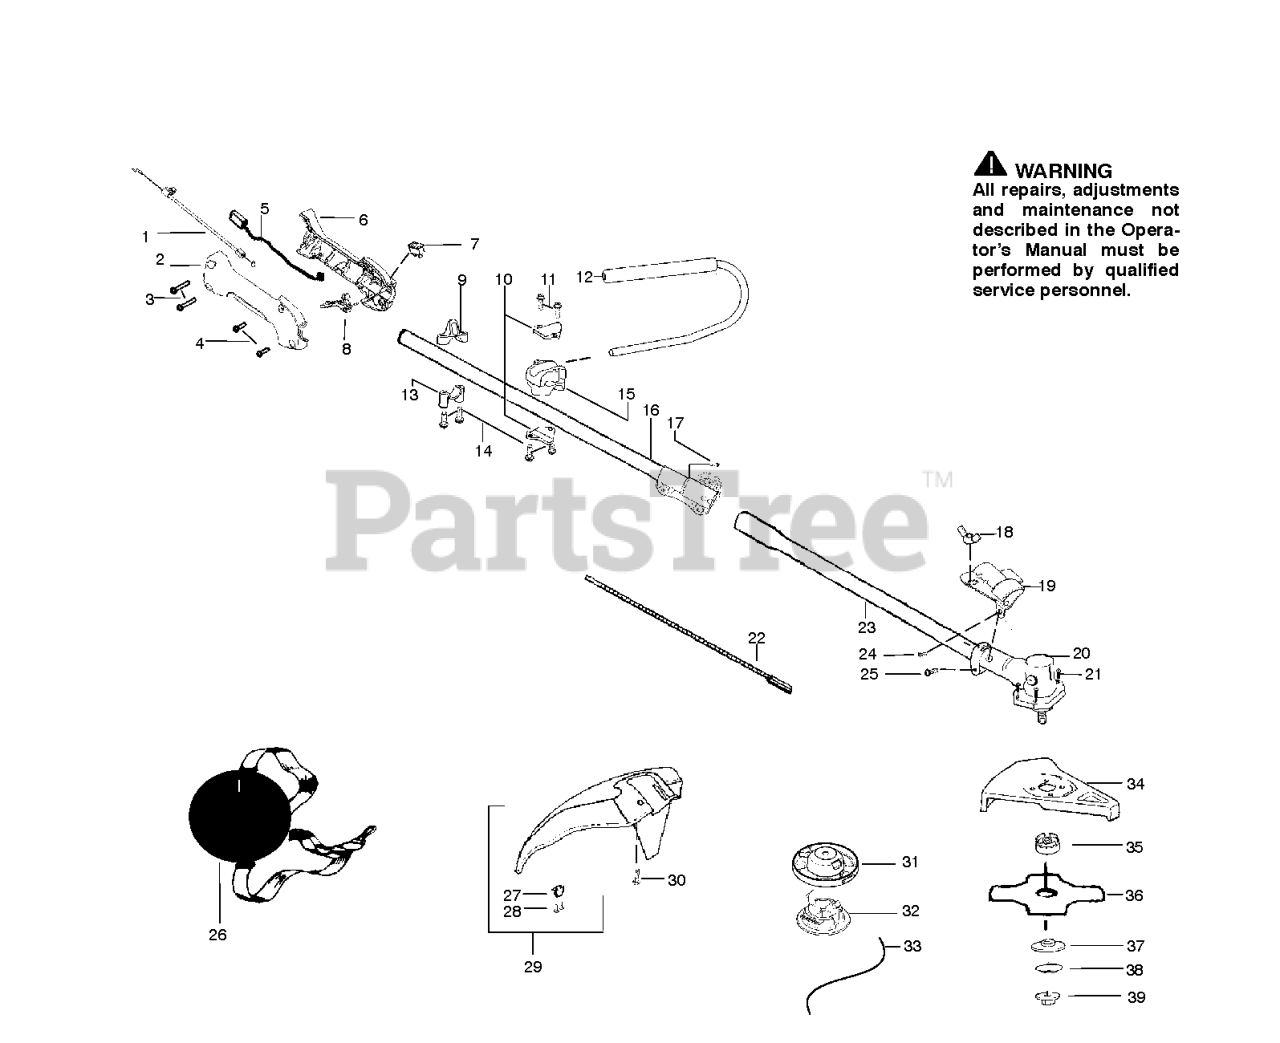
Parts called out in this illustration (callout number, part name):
1	ASSEMBLY
2	HSG THROTTLE RIGHT BLACK
3	SCREW #10 PLASTITE 1.362
4	Screw-Shroud/Blower Hsg.
5	Assy.-Wire
6	HSG THROTTLE LH BLACK EURO
7	Kit-Switch (momentary)
8	THROTTLE TRIGGER PPR GOLD
9	Clamp-Harness (upper)
10	Bracket--Handlebar
11	SCREW-10-14 X 13/16 (PL
12	Assy.-Handlebar
13	Clamp-Harness (lower)
14	Screw - 10-14 x .095
15	Clamp-Handlebar ( 1")
16	Assy-Upper Shaft
17	Screw (12-24 x .480)
18	Wingnut-Handle/Shield
19	Bracket - Shield SST
20	Assy - Gearbox 1" Brushcutter
21	SCR 10-24 MS LDK PAN PH
22	FLEXSHAFT SPLIT BOOM
23	ASSY DRIVESHAFT LOWER BC/SST
24	SCREW 8-16 X 9/16 (PLAS
25	SCREW - CARB. ADAPTOR
26	Assy--Shoulder Strap
27	Limiter - Line
28	Screw-Shroud/Blower Hsg.
29	Kit-Shield Assy.
30	Bolt - 1/4-20 x 1-1/4
31	TRIMMER HEAD
32	TNG VII SPOOL for PP125 .095"
33	.095" TRIMMER LINE - 100'
34	ASSY, SHIELD, BLADE
35	Dust cup - Blade
36	Assy. - Blade
37	Washer-Blade Retaining
38	Washer - Belleville
39	Nut - Flange (L.H.)
